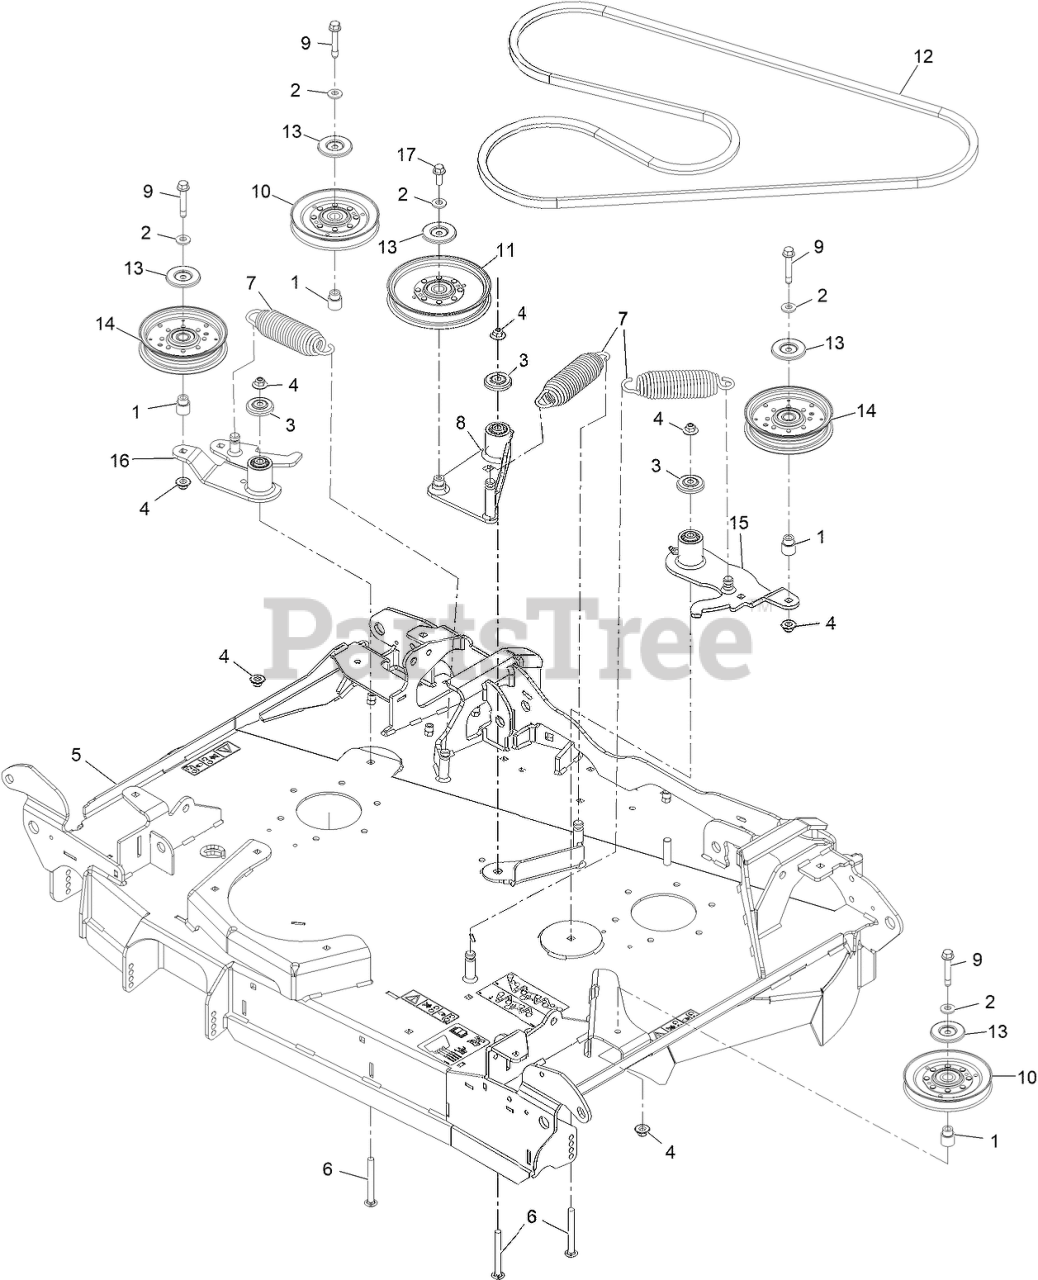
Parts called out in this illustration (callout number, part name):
1	BUSHING-IDLER
2	WASHER-BELLEVILLE
3	GUARD-TOP
4	Nut-Nyloc 3/8-16 Flg
5	ASM-Deck, Ctr 96/144
6	BOLT-SHOULDER, CARRIAGE 3/8-16 X 3 1/2
7	SPRING-EXTENSION
8	IDLER ARM ASM
9	SCREW-HHF
10	IDLER-V
11	IDLER-PULLEY
13	SHIELD-DUST
14	PULLEY-IDLER, FLAT
15	IDLER ASM
16	IDLER ASM
17	SCREW-HHF 3/8-16 X 1
